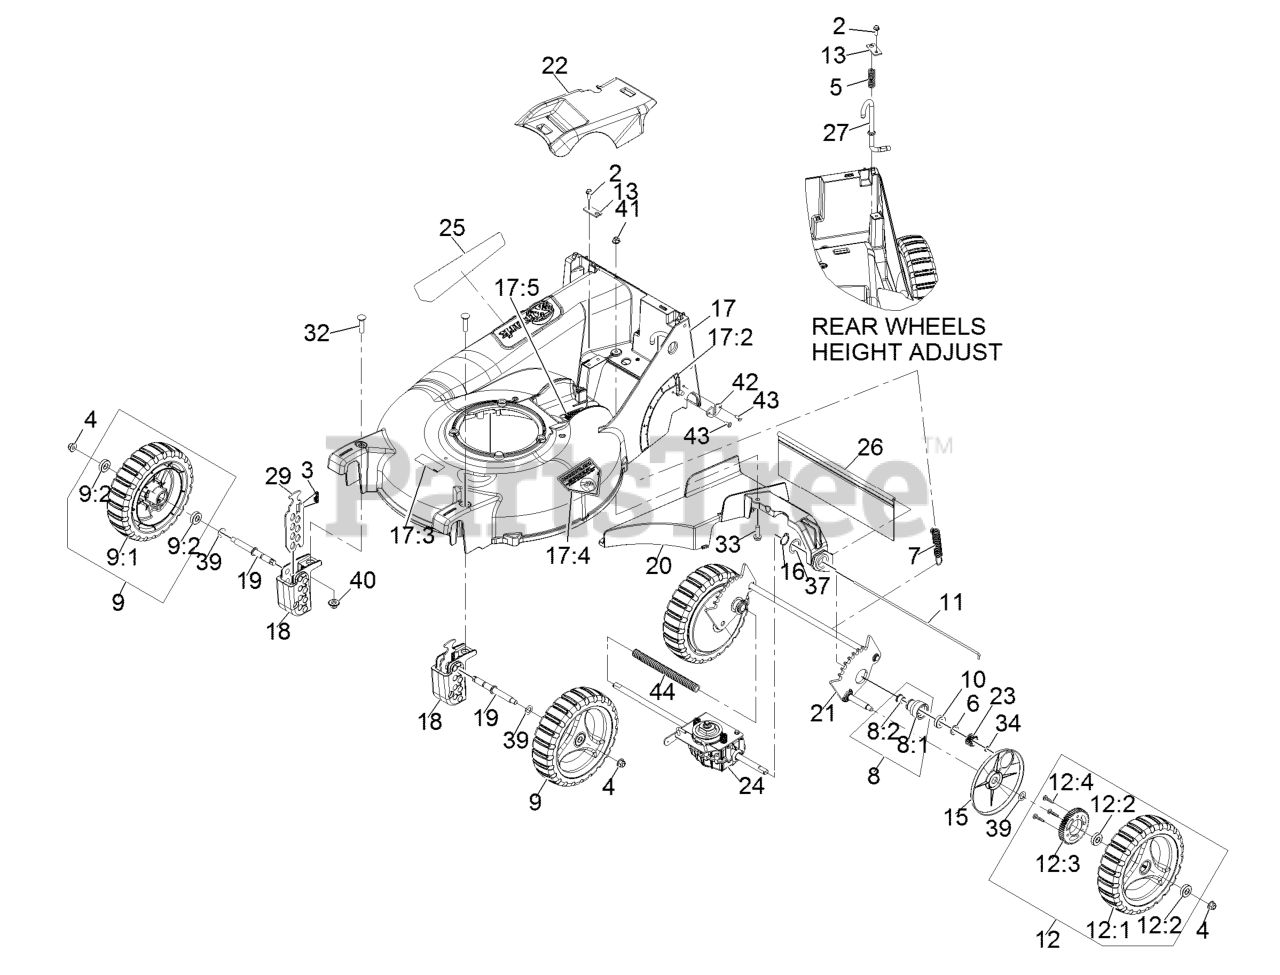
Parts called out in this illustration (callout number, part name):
2	SCREW-HWH
3	SPRING-COMPRESSION
4	NUT-HF, NI
5	SPRING-COMPRESSION
6	SPACER-BUSHING
7	SPRING-EXTENSION
8	HOUSING ASM
8:1	HOUSING-BEARING
8:2	BEARING-FLANGE
9:2	BEARING-BALL
10	BEARING-BALL
11	ROD,SHIELD
12:2	BEARING-BALL
12:4	SCREW-DRIVE
13	BRACKET,MOUNT
15	COVER,GEAR
16	RING-RETAINING
17	DECK W/DECALS
17:2	DECAL-HEIGHT OF CUT
17:3	DECAL-BLADE
17:4	DECAL-DANGER
17:5	DECAL-COVER MISSING
18	BLOCK,FRONT QUADRANT
19	AXLE-WHEEL
20	BRACKET-TRANSMISSION AND
21	WLD,REAR AXLE P21
22	COVER,BELT
24	ASM,TRANSMISSION W/BRACKE
25	DECAL-COMM 21 S-SERIES
26	SHIELD-TRAILING P21
27	ROD-HEIGHT ADJ P21
29	PLATE, FRONT HEIGHT
32	SCREW-CARR
33	SCREW-HWHTF
34	RING-RETAINING
39	WASHER-PLAIN
40	Nut-Nyloc 3/8-16 Flg
41	NUT-HF, NI
42	PLATE,WEAR
43	RIVET-BLIND
44	COVER-SHAFT, DRIVE
